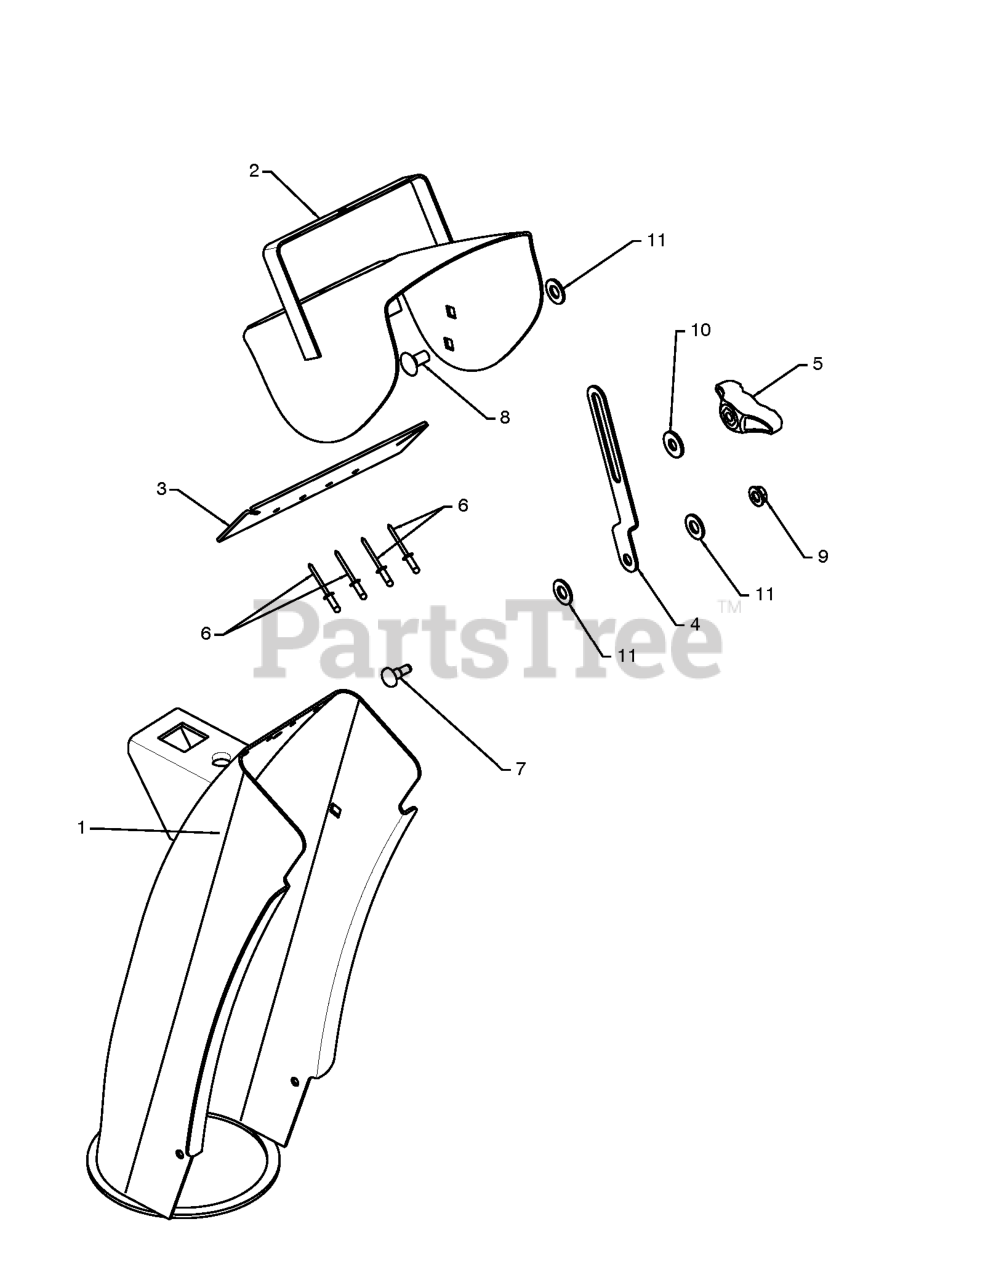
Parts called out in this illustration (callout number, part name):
1	CHUTE.WELDMENT
2	DEFLECTOR.WELDMENT.PNT.ORANGE
3	SEAL.DEFLECTOR
4	STRAP, CHUTE
5	KNOB, DEFLECTOR
6	RIVET BLIND
7	SHOULDER BOLT
8	BOLT
9	NUT.HEX.FLANGE.1/4
10	WASHER.20X8.5
11	WASHER, NYLON FRICTION
